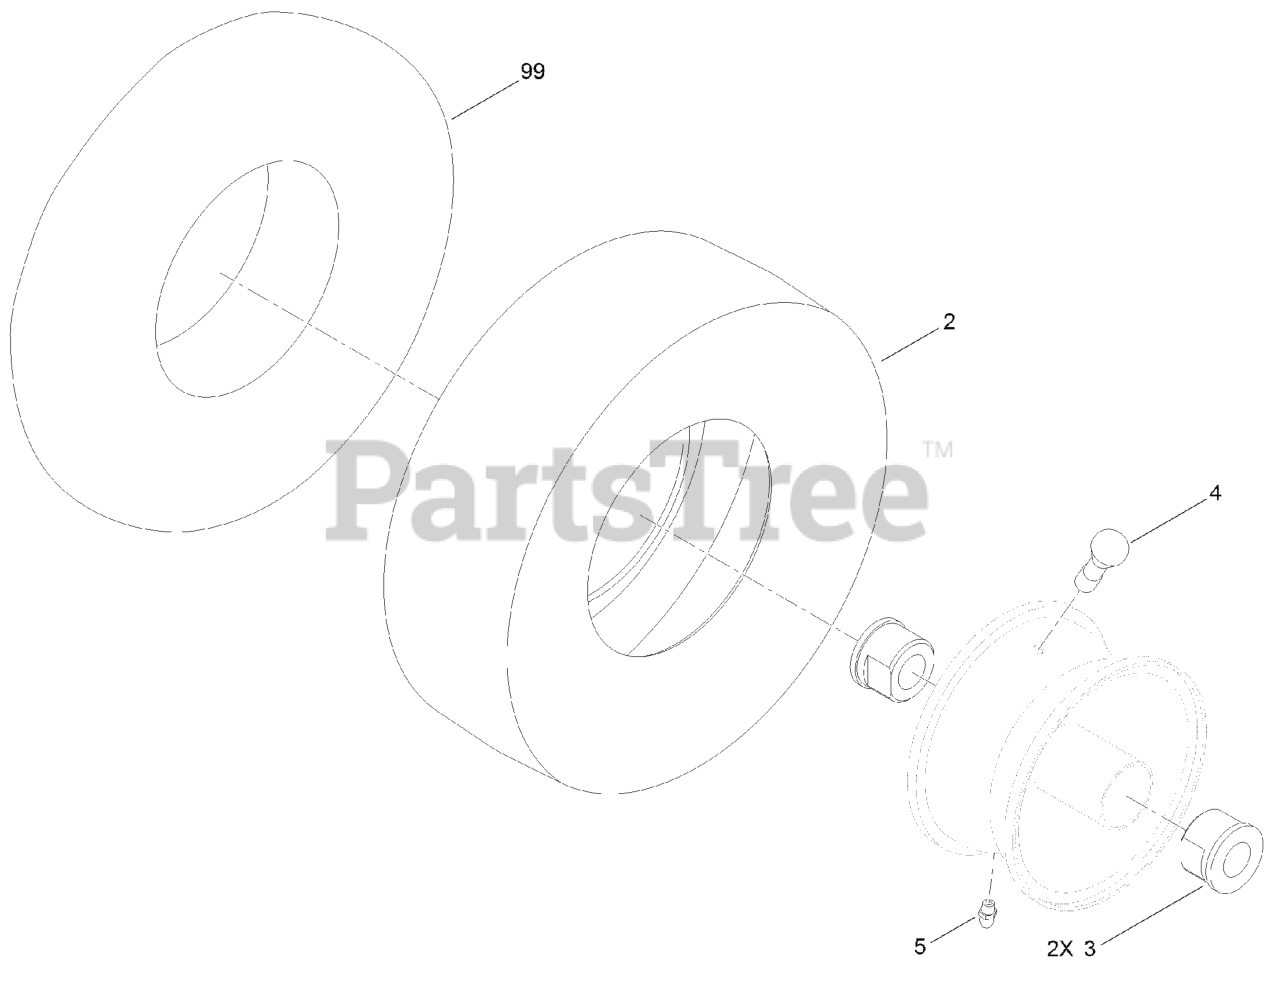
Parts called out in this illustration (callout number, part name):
3	BUSHING-FLANGE
4	Stem-Valve
5	FITTING-GREASE
99	TUBE-INNER
